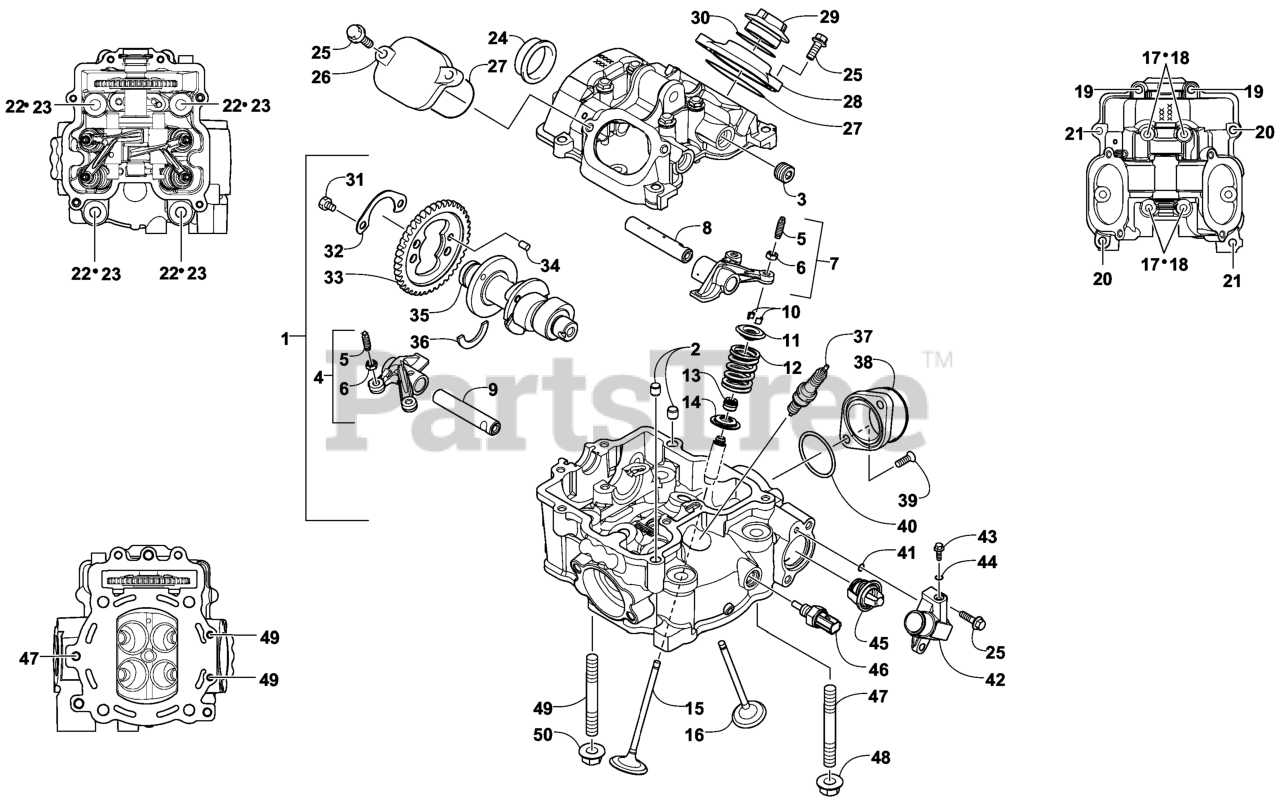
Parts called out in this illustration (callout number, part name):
1	HEAD-CYLINDER
2	DOWEL-SLEEVE
4	ARM-VALVE ROCKER, EXHAUST
8	SHAFT-ROCKER ARM, INTAKE
10	KEEPER-VALVE
11	RETAINER-UPPER, SPRING
12	SPRING-VALVE
13	SEAL-VALVE STEM
14	SEAT-LOWER, VALVE SPRING
15	VALVE-INTAKE
16	HARNESS,WIRING METRO
17	SCREW-HFH
18	SEAL-FASTENER
19	SCREW-HFH
20	SCREW-HFH
21	SCREW-HFH
22	ASM,HOUSING CUTTER
23	WASHER-STEEL
25	SCREW-HFH
26	CAP-VALVE INSPECTION
28	CAP-VALVE INSPECTION (WIT
29	PLUG-INSPECTION CAP (WITH
31	SCREW-HH
32	WASHER-LOCK
33	CAM-SPROCKET
34	PIN-SOLID DOWEL
35	CAMSHAFT ASM
36	PLATE-RETAINER, CAM
37	SPARK PLUG
38	FLANGE-INTAKE MANIFOLD
39	SCREW-TSPH
42	COVER-THERMOSTAT
43	SCREW-HFH
45	THERMOSTAT (65 DEG)
46	SENSOR-WATER TEMP
50	NUT-HHF
